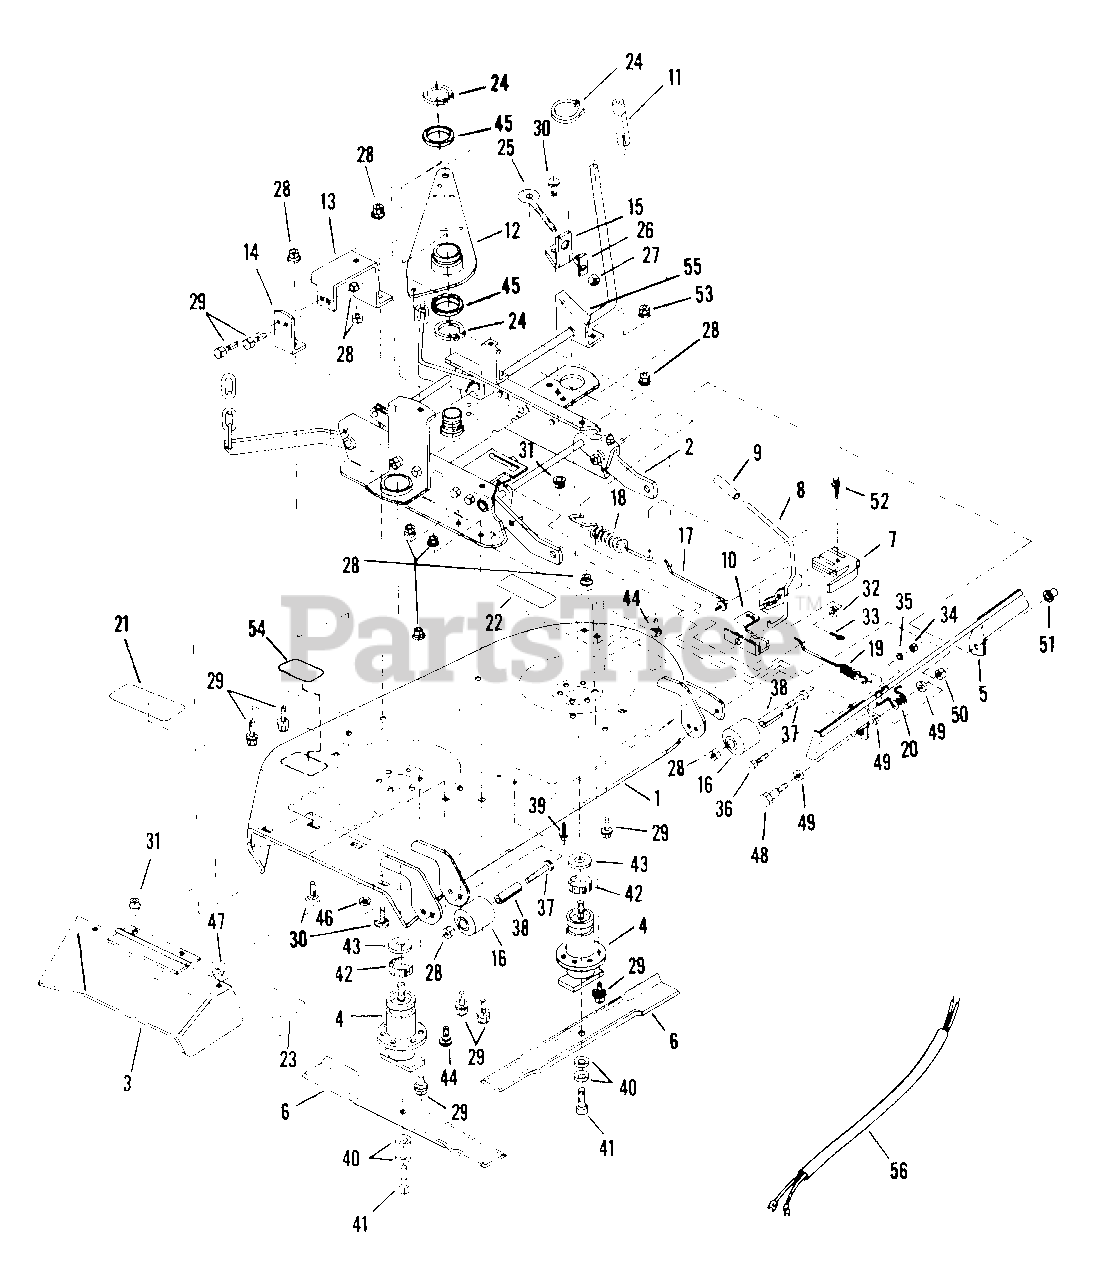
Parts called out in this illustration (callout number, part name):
1	ASSEMBLY, Deck
2	ASSEMBLY, Rail
3	ASSEMBLY, Side Chute
4	ASSEMBLY, Spindle
5	ASSEMBLY, Pedal
6	BLADE, 21"
7	SWITCH
8	ENGAGE LEVER
9	GRIP, Handle
10	BRACKET
11	GRIP, lever
12	IDLER ARM
13	SUPPORT, Idler
14	BRACKET
15	ANCHOR
16	ROLLER
17	ROD, Idler
18	SPRING, Belt
19	SPRING, Latch
20	SPRING, Pedal
21	DECAL, Caution (Rotating Blades)
22	DECAL, Caution (Rotating Blades)
23	DECAL, Danger (Keep Hands &. Feet Away)
24	RING, 2" External Retaining
25	EYE-BOLT
26	T-NUT
27	NUT, 1/4 Hex
28	NUT, Hex Lock 3/8-24
29	CAPSCREW, 3/8-24x3/4" Hex Head
30	CARRIAGE BOLT, 5/16-18x5/8"
31	LOCKNUT, Hex Flange 5/16-18
32	WASHER, 1/4 SAE
33	PIN, Cotter 3/32x3/4
34	NUT, 1/4-28 HEX
35	WASHER, 1/4 Internal Tooth Lock(1/4)
36	CAPSCREW, 1/4-28x1" Hex Head
37	CAPSCREW, 3/8-24x3 3/4" Hex Head
38	SPACER(2)
39	SCREW, Self Tapping 1/4-20x5/8
40	WASHER, Cone
41	CAPSCREW, 3/8-24x1" Hex Head
42	RING, Tolerance
44	CARRIAGE BOLT, 3/8-16x3/4"
45	WASHER, 2" I.D.
46	RETAINER, Bolt 5/16
47	WINGNUT, 5/16-18
48	BOLT, Shoulder 3/8-24x1 3/4
49	WASHER, 1/2 SAE
50	NUT, Hex 3/8-24
51	NUT, Push 1/2"
52	SCREW, Self Tapping #10x1"
53	NUT, 3/8-16 Hex Lock
54	PLATE, Model Number
55	BRACKET, Height Indicator
56	HARNESS, Deck Interlock Wiring
